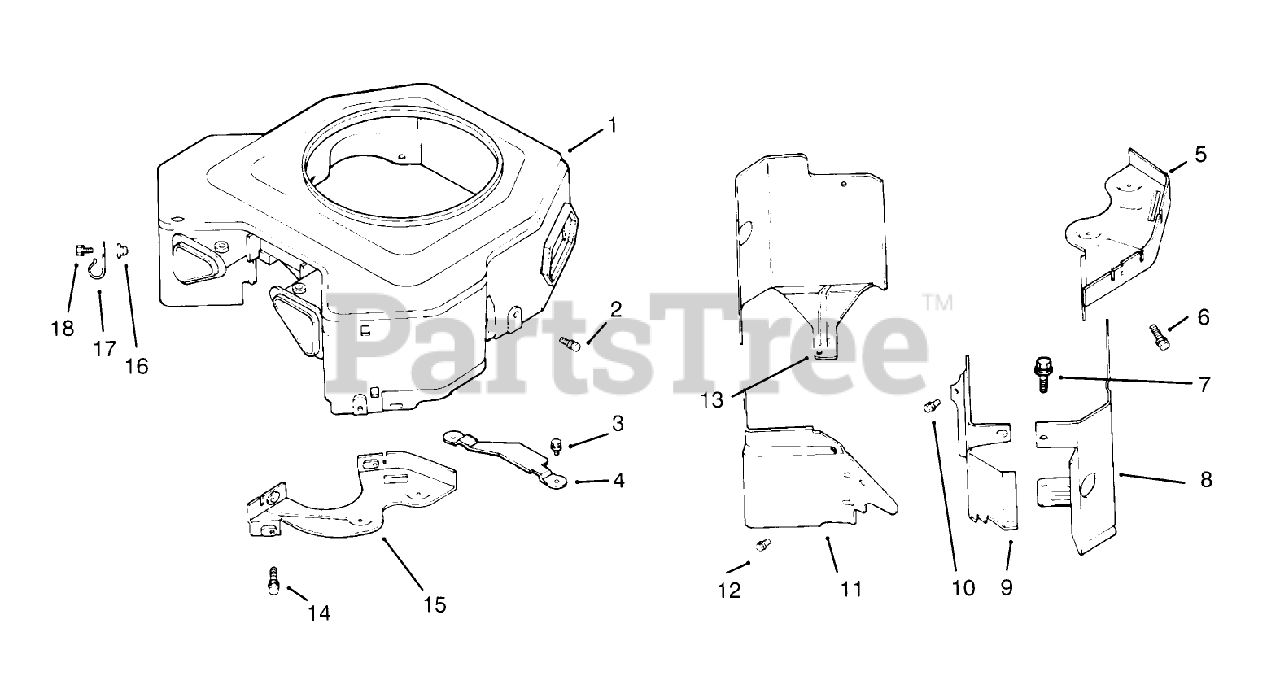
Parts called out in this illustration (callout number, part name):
1	Housing-Blower ASM (Only C)n: 72103, 72083)
4	Guard-Flywheel (Only On: 72103, 72083)
5	Plate-Backing #2 side
8	Baffle Cylinder #2 Side
9	Baffle-Valley #1 Side (Only On: 72103)
11	Baffle-Valley #2 Side (Only On: 72103, 72083)
13	Baffle-Cylinder #1 Side (Only On: 72103)
15	Plate-Backing #1 Side (Only On: 72103, 72083)
17	Clip-Cable (Only On: 72103)
